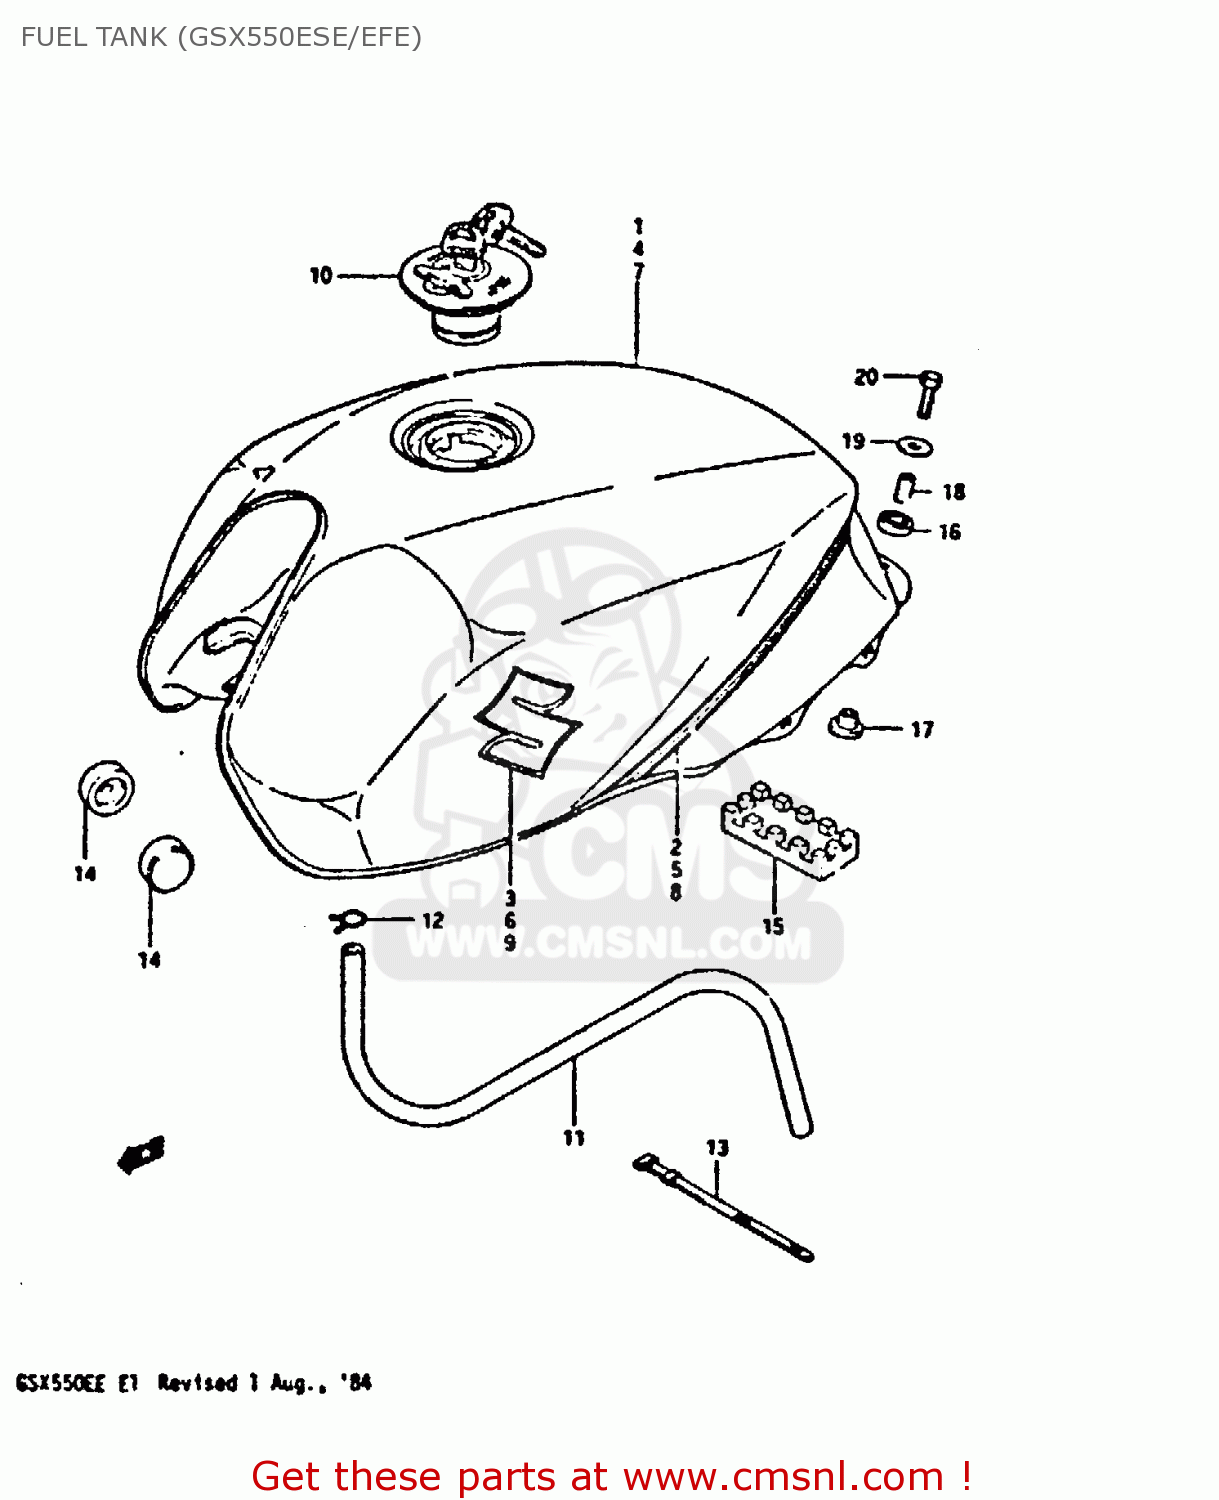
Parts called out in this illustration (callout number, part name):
1	TANK ASSEMBLY,FUEL
2	TAPE SET,FUEL TANK
3	EMBLEM
4	TANK ASSY, FUEL
5	TAPE SET, FUEL TANK
6	EMBLEM
7	TANK ASSY, FUEL
8	TAPE SET, FUEL TANK
9	EMBLEM
10	CAP ASSY,FUEL TANK
11	HOSE,FUEL
12	CLIP
13	CLAMP(L:187)
14	CUSHION
15	CUSHION,FUEL TANK
16	CUSHION
17	CUSHION
18	SPACER (6.4X9X20)
19	WASHER (6.5X24X1.6)
20	BOLT
